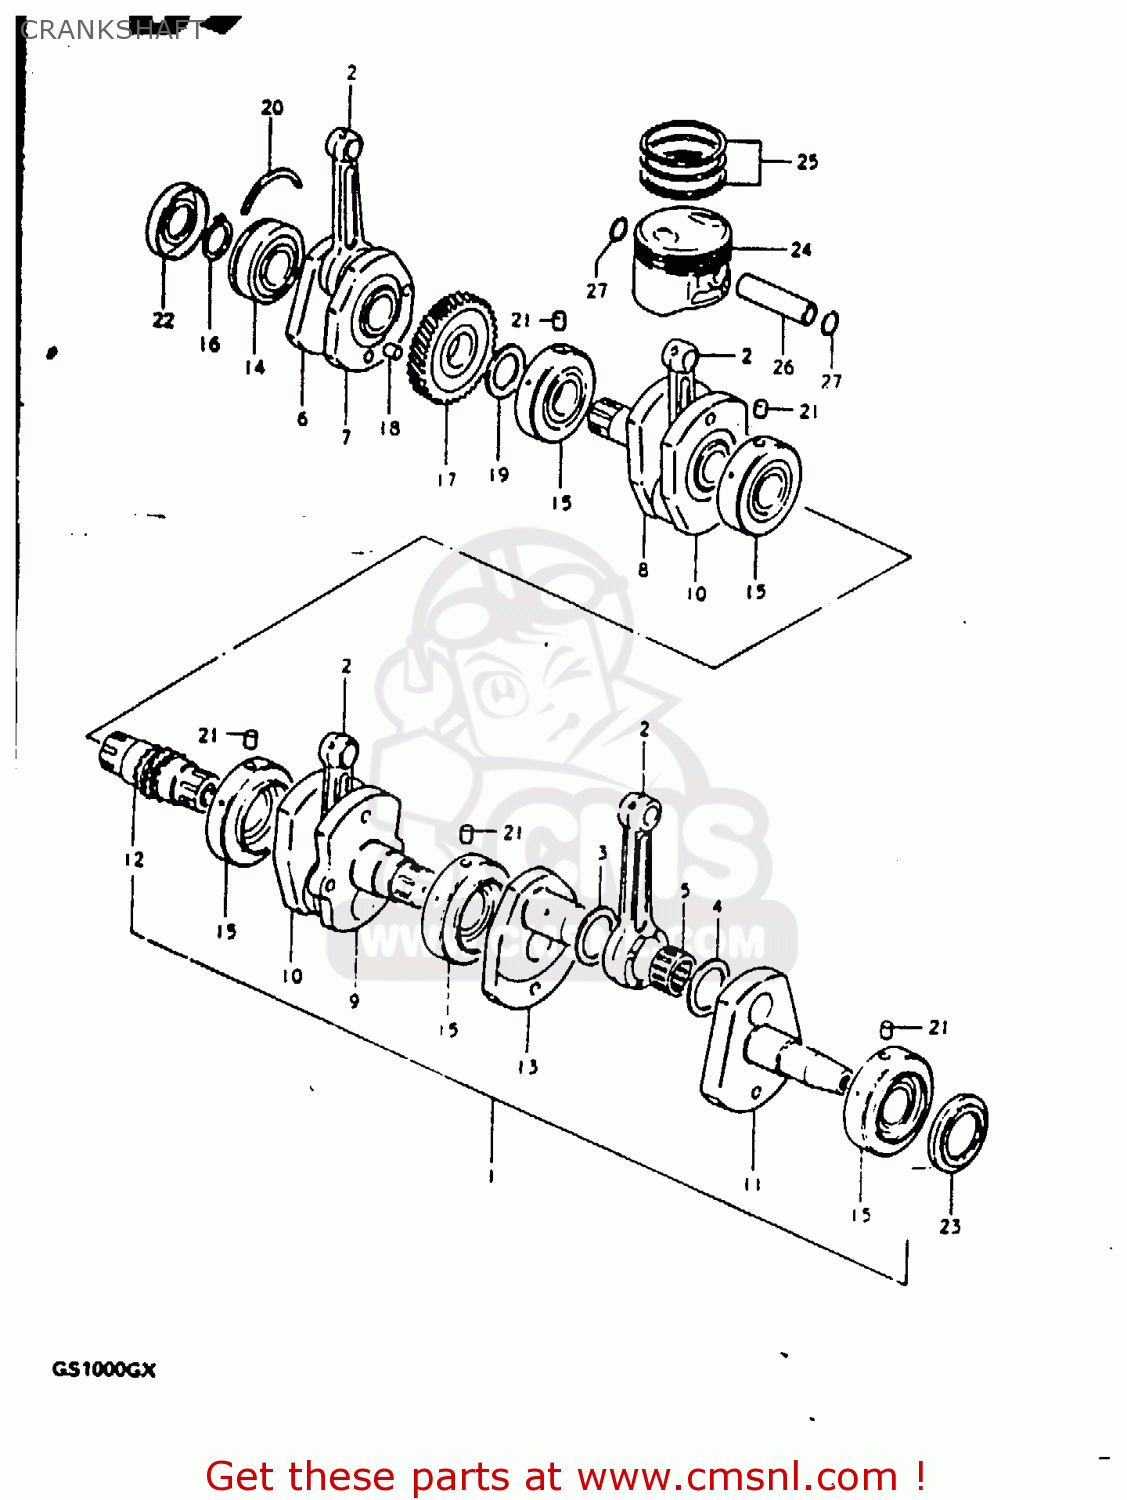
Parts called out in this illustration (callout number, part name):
1	CRANKSHAFT ASSEMBLY
2	ROD,CONNECTING
3	WASHER (29X48X2)
4	WASHER (29X48X1)
5	BEARING(29X39X20)
6	CRANKSHAFT
7	CRANKSHAFT
8	CRANKSHAFT
9	CRANKSHAFT
10	WEB,CRANK,MIDDLE
11	CRANKSHAFT,LEFT
12	SHAFT,TIMING CHAIN DRIVE
13	WEB,CRANK
14	BEARING(30X72X19)
15	BEARING
16	CIRCLIP,30MM
17	GEAR,PRIMARY DRIVE
18	PIN
19	WASHER
20	C RING
21	PIN
22	SEAL,OIL(30X72X11)
23	SEAL,OIL(47.3X60X6.5)
24	PISTON
25	RING SET,PISTON
26	PIN,PISTON (18MM)
27	CIRCLIP,PISTON PIN
